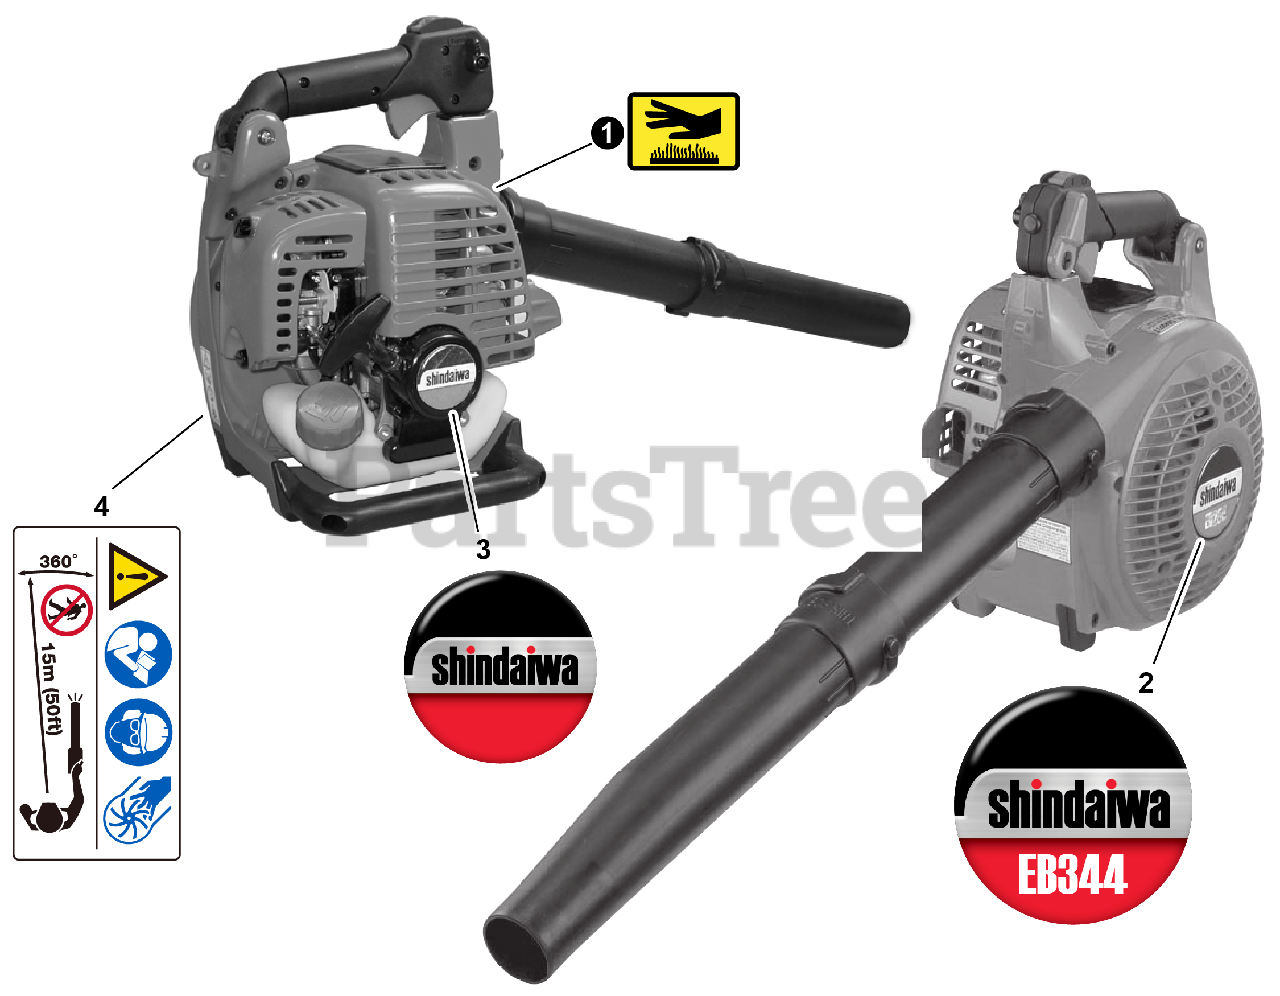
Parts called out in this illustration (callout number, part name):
1	LABEL, CAUTION - HOT
2	LABEL, EB344
3	LABEL, SHINDAIWA
4	LABEL, CAUTION
